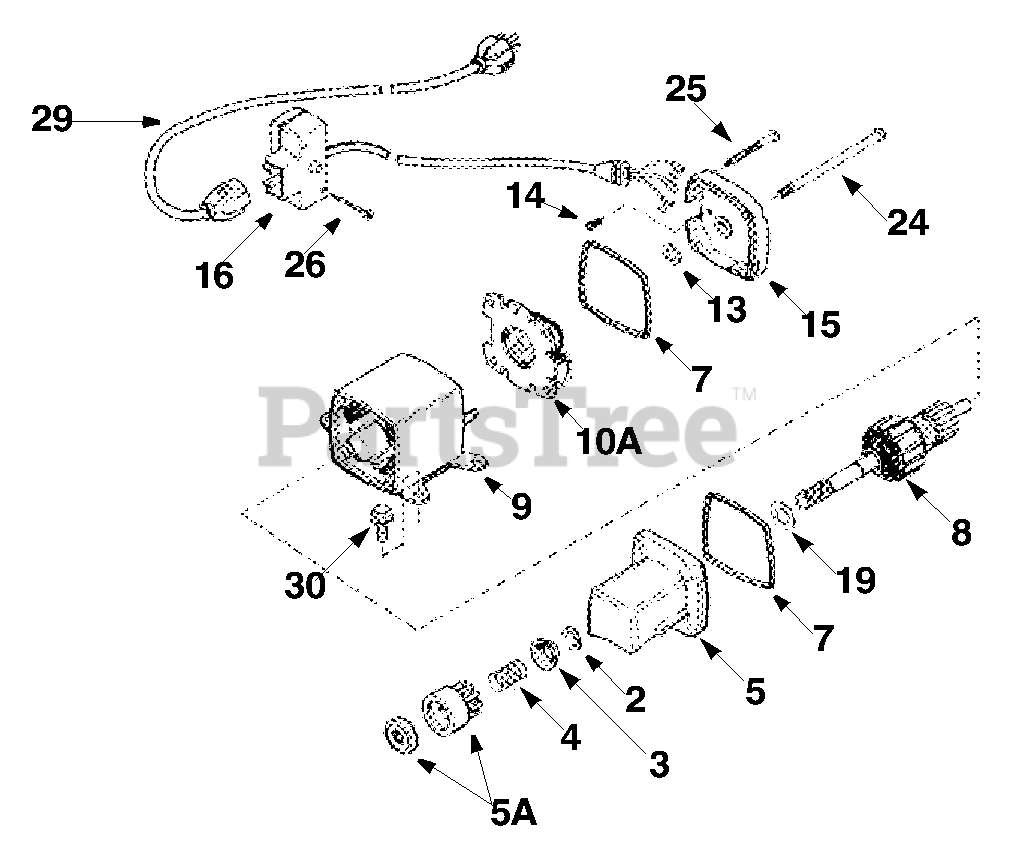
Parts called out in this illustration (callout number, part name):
2	Retainer Ring
3	Spring Retainer
4	Anti-drift Spring
5A	Nut & Gear
7	"O" Ring
8	Armature
9	Housing Ass'y. (Complete Motor)
10A	Brush & Spring Card Ass'y.
13	Thrust Washer
14	Ground Screw
15	Commutator End Cap Ass'y.
16	Switch Box Ass'y.
19	Thrust Washer
24	Case Bolt
25	Grounding Screw
26	Screw, 6-32 x 2-1/2"
26	Screw, 12-16 x 5/8"
29	Extension Cord (10'6")
30	Screw, Torx T-30, 1/4-20 x 23/32"
